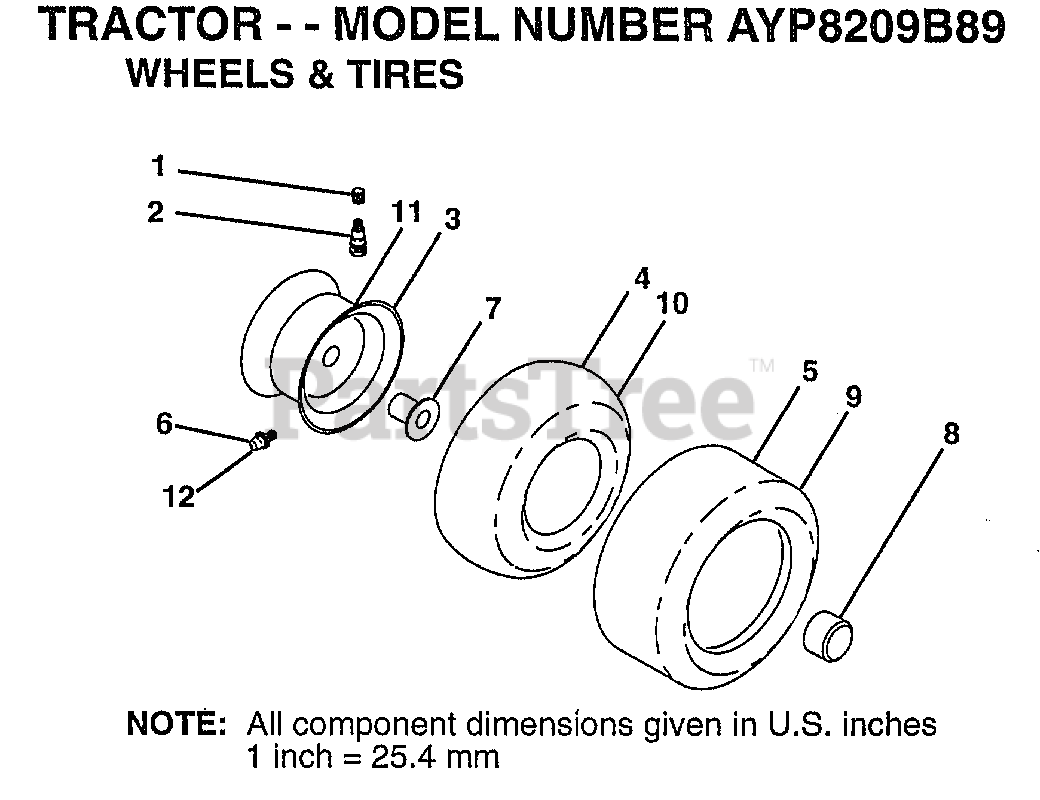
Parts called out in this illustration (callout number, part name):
1	VALVE CAP
2	VALVE STEM LT
3	"RIM ASM 8"" FRT"
4	TUBE.16X6.5/7.5-8
6	FITTING LT
7	"FLANGE, BEARING"
8	HUB CAP
10	TUBE.23X8/10-12
11	"RIM ASM 12"" REAR"
12	ZERK FITTING M
